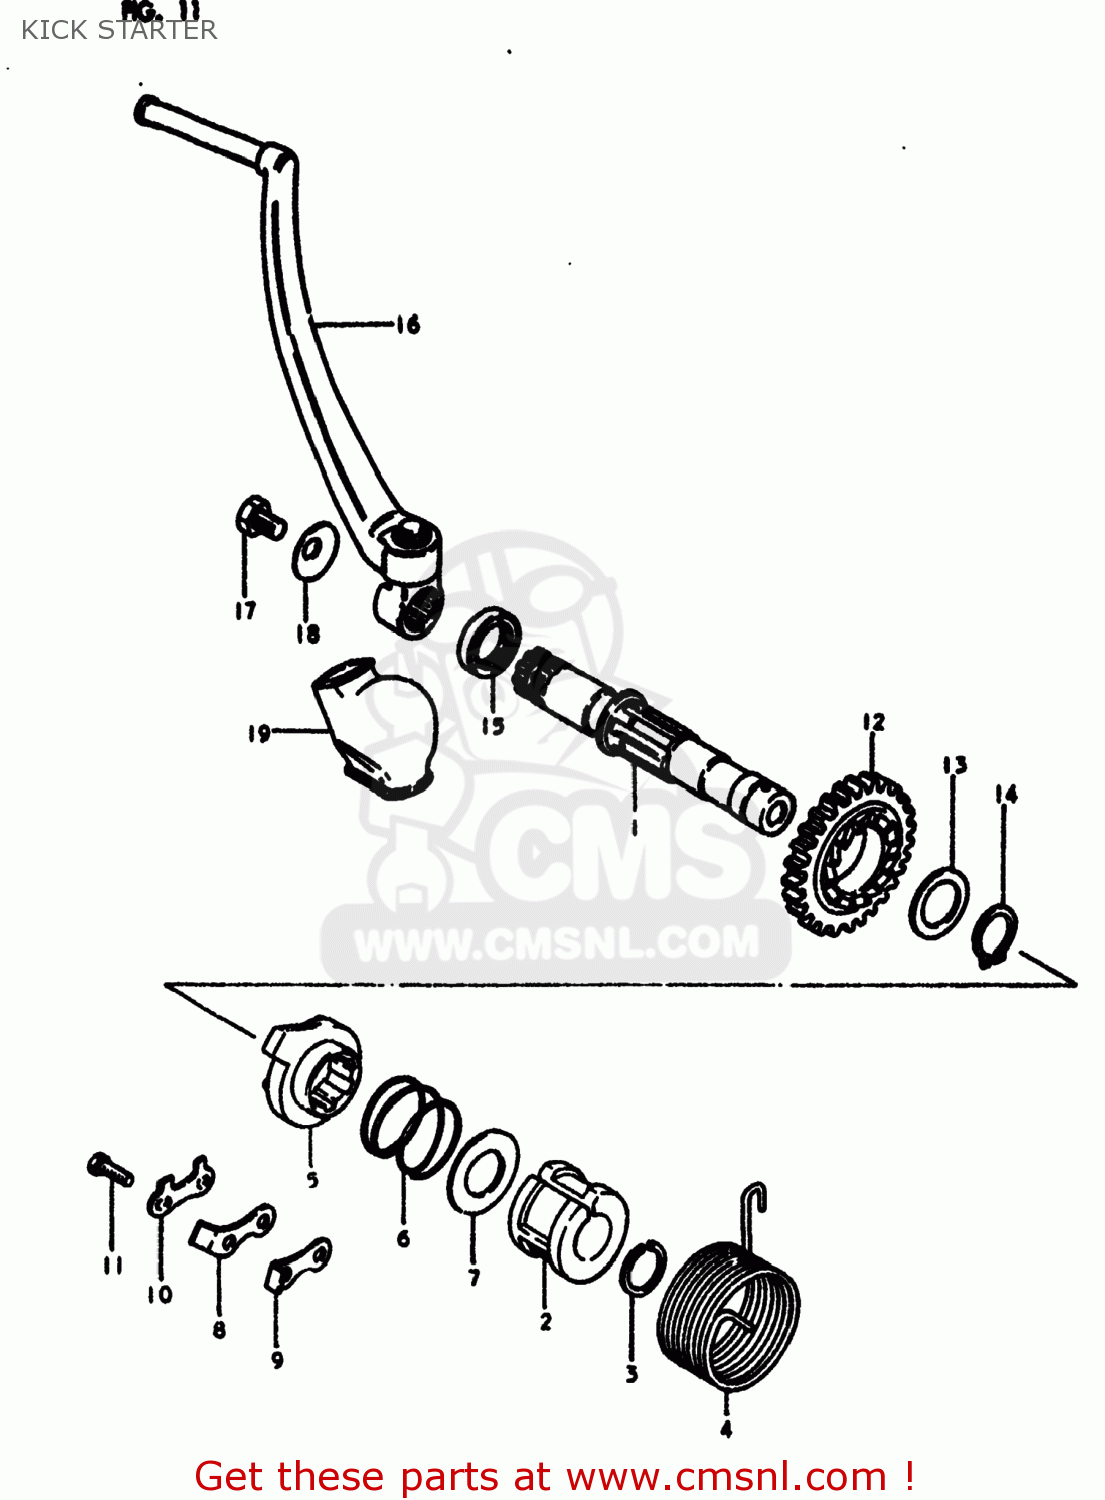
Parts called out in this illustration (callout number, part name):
1	SHAFT,KICK STARTER
2	GUIDE,KICK STARTER SFT SPRING
3	CIRCLIP
4	SPRING
5	STARTER,KICK
6	SPRING
7	WASHER
8	GUIDE,KICK STARTER
9	STOPPER,KICK STARTER
10	WASHER
11	BOLT
12	GEAR,KICK STARTER DRIVE
13	SHIM
14	CIRCLIP
15	SEAL,OIL(20X27X5)
16	LEVER ASSEMBLY,KICK STARTER
17	BOLT, UPPER
18	WASHER (6X20X1.5)
19	COVER,KICK LEVER JOINT
